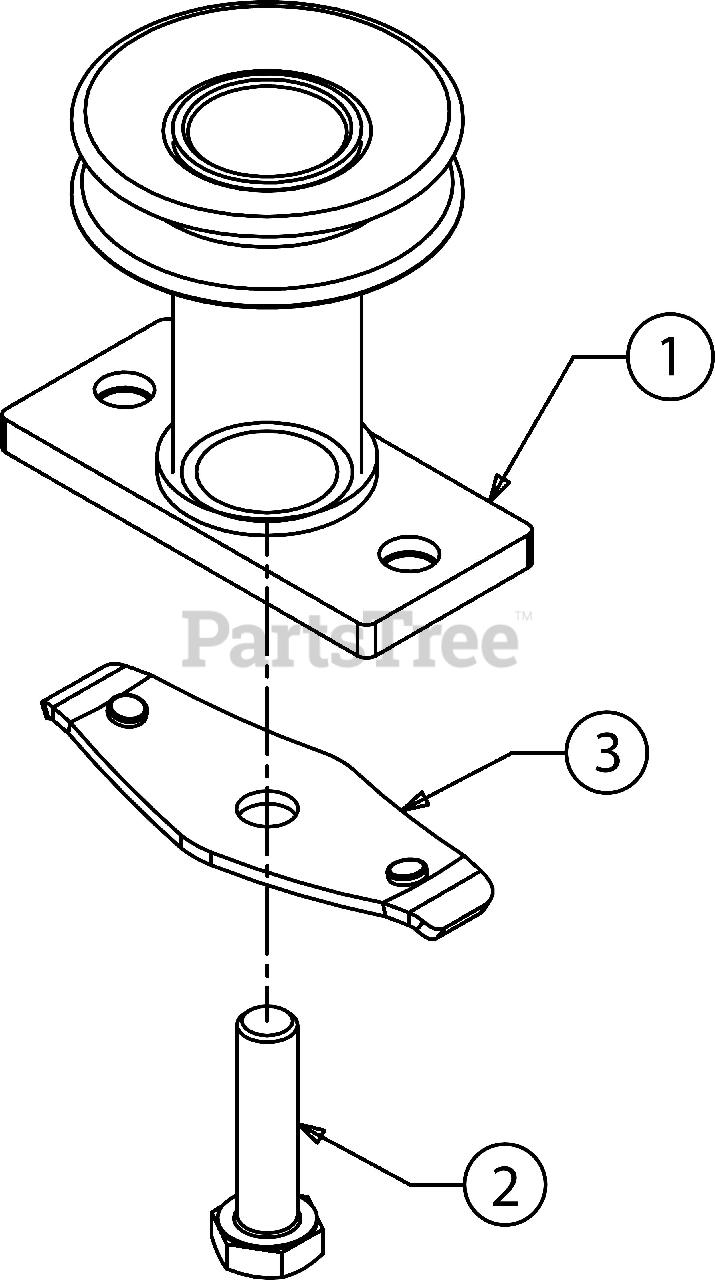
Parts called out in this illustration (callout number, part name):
1	BLADE ADAPTER
2	SCREW 3/8-24 X 1.50 GR8
3	BLADE BELL SUPPORT
